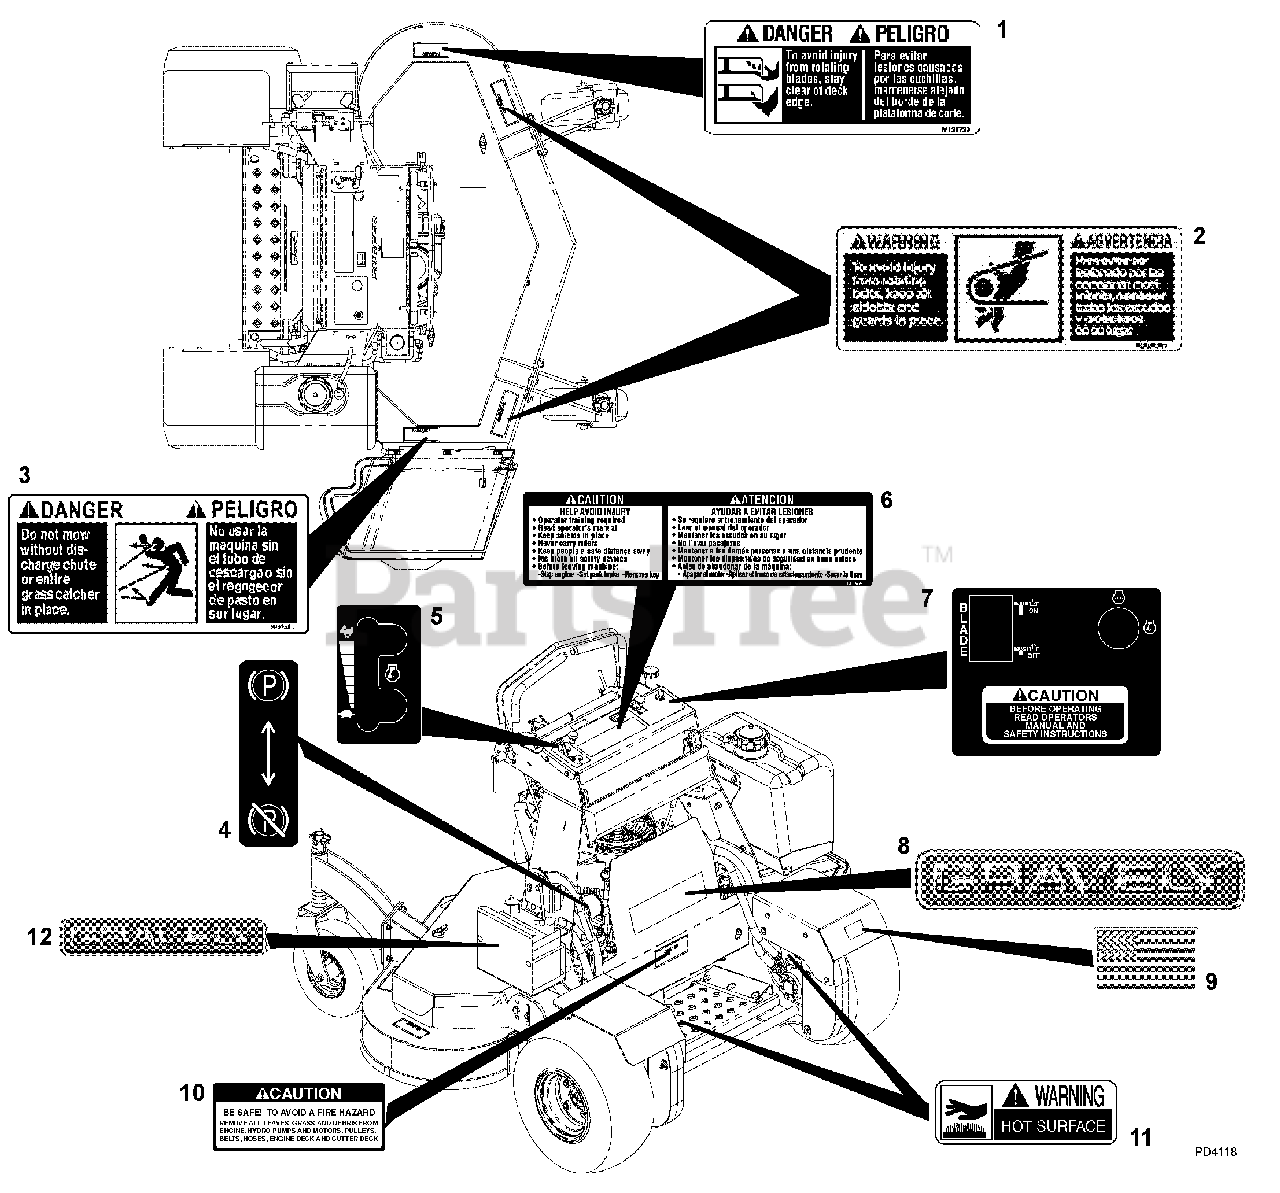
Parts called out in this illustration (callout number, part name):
1	Decal, Danger - Blade Contact
2	Decal, Danger - Rotating Belts
3	Decal, Danger - Rotating Blades
4	Decal, Park Brake
5	Decal, Throttle
6	Decal, General Caution
7	Decal, PTO/Ignition
8	Decal, 15" Gravely Logo
9	Decal, American Flag
10	Decal, Caution - Fire Hazard
11	Decal, Warning, Hot Surface
12	Decal, Gravely Logo
